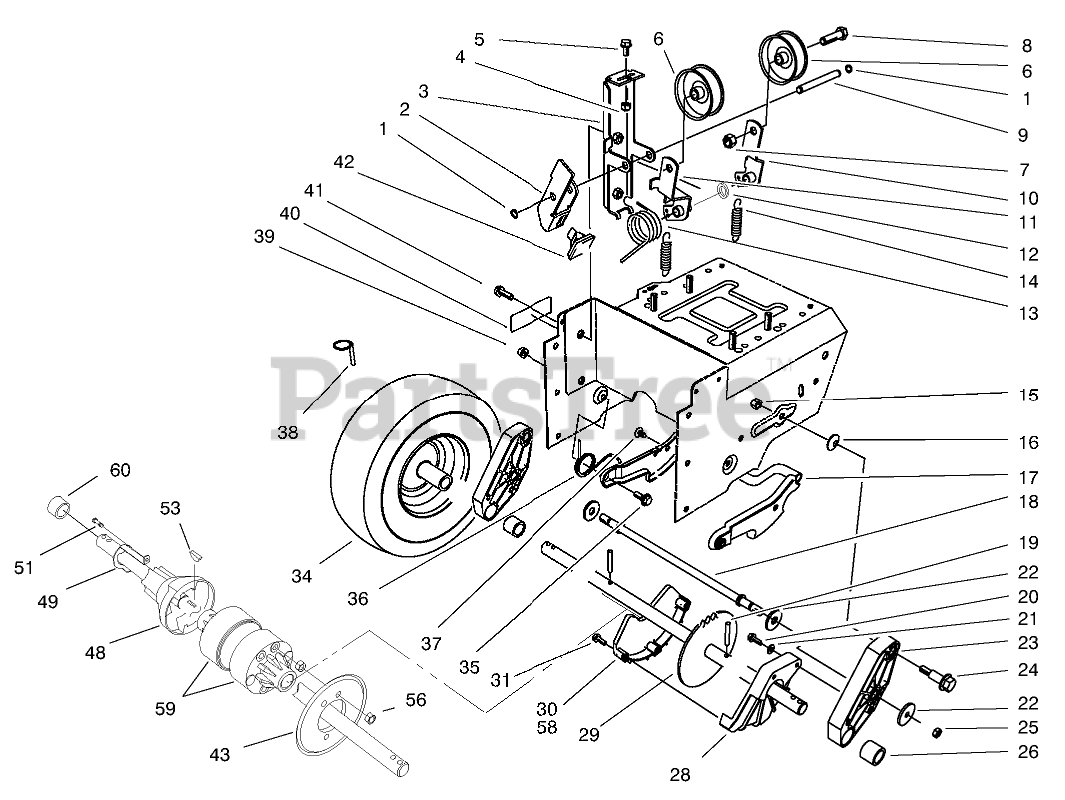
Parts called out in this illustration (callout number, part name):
1	RING-RETAINING
2	ARM-BRAKE
3	IDLER ARM BRACKET ASM
4	NUT-LOCK, NI
5	SCREW-HHF
6	PULLEY-IDLER
7	NUT-LOCK, NI
8	SCREW-HH
9	PIN-IDLER
10	TRACTION IDLER ARM ASM
11	IMPELLER IDLER ARM ASM
12	WASHER-FLAT
13	TORSION SPRING
14	SPRING-EXTENSION
15	NUT-LOCK, NI
16	WASHER-SPRING
17	Latch-Arm
18	ROD-LATCH
19	PIN-ROLL, SLOTTED
20	SCREW-HWH
21	WASHER-FLAT
22	WASHER-SUPPORT
23	Pivot Arm Assembly (Incl. Ref. # 26)
24	BOLT-SHOULDER
25	NUT-LOCK, NI
26	BUSHING-AXLE
28	GUARD-CHAIN, LH
30	GUARD-CHAIN, RH
31	SCREW-PPH
34	WHEEL & TIRE ASSEMBLY
35	SCREW-SHOULDER
36	SPRING-LATCH, TORSION
37	FASTENER-PANEL
38	PIN-LYNCH
39	NUT-LOCK, NI
40	DECAL-WARNING
41	SCREW-HHF
42	PAD-BRAKE
43	SPROCKET, 32 T
44	DIFFERENTIAL ASM
48	COUPLING-DIFFERENTIAL
49	SPRING-LOCKOUT
51	SCREW-HWH
53	KEY-WOODRUFF
56	NUT-LOCK, NI
58	GUARD-CHAIN
59	Differential Asm (Incl. Ref. #44-57)(Model 38590 Only)
60	SPACER
